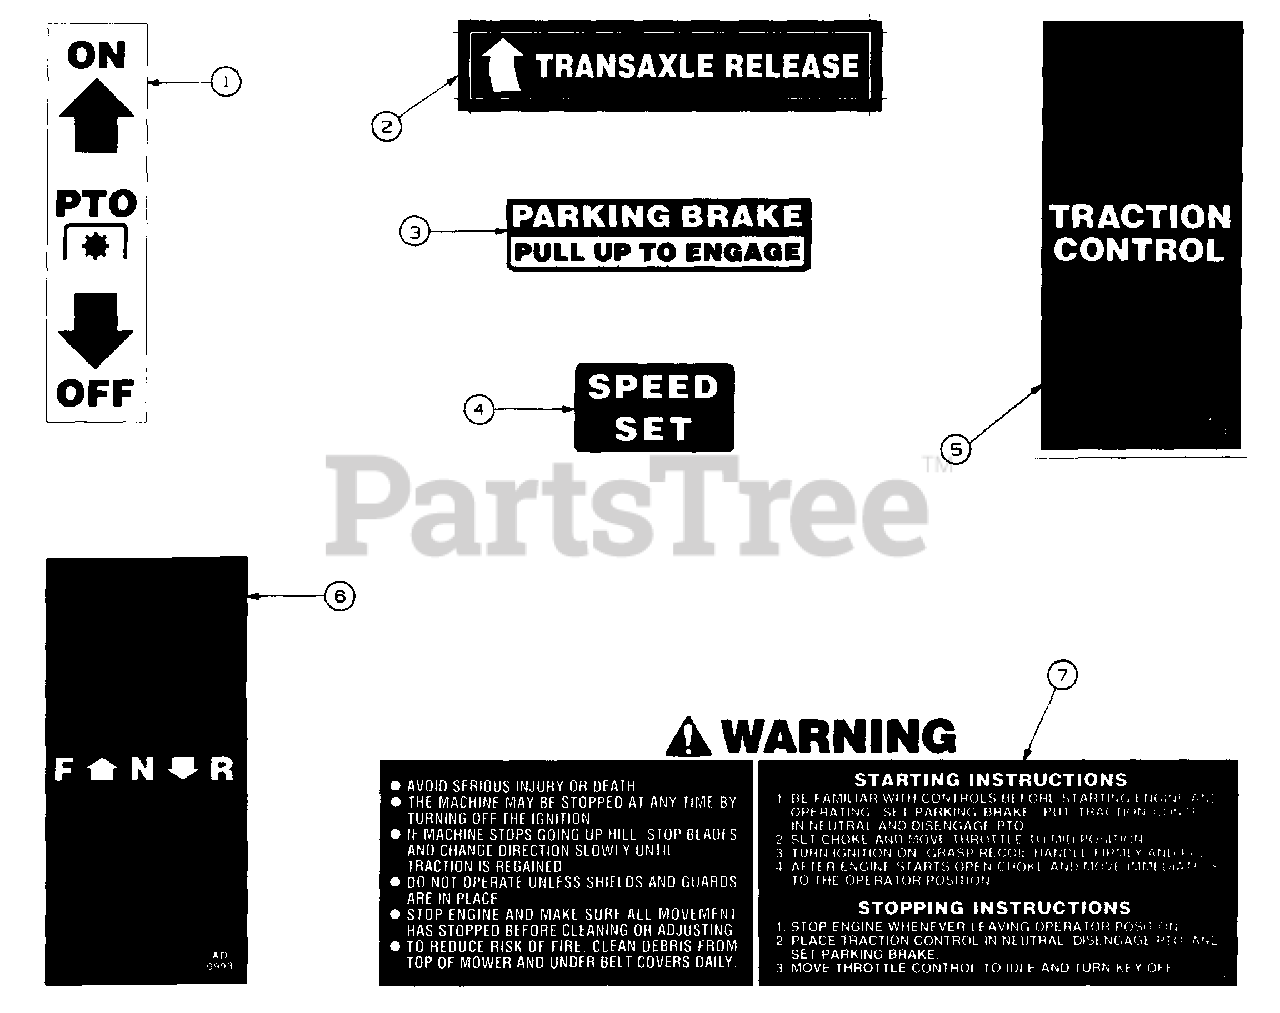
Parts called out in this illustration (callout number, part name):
1	Graphic, Manual PTO
2	Graphic, Transaxle Release
3	Graphic, Park Brake
4	Graphic, Speed Set
5	Graphic, Traction Control
6	Graphic, F-N-R
7	Graphic, Fuel Tank Warning
